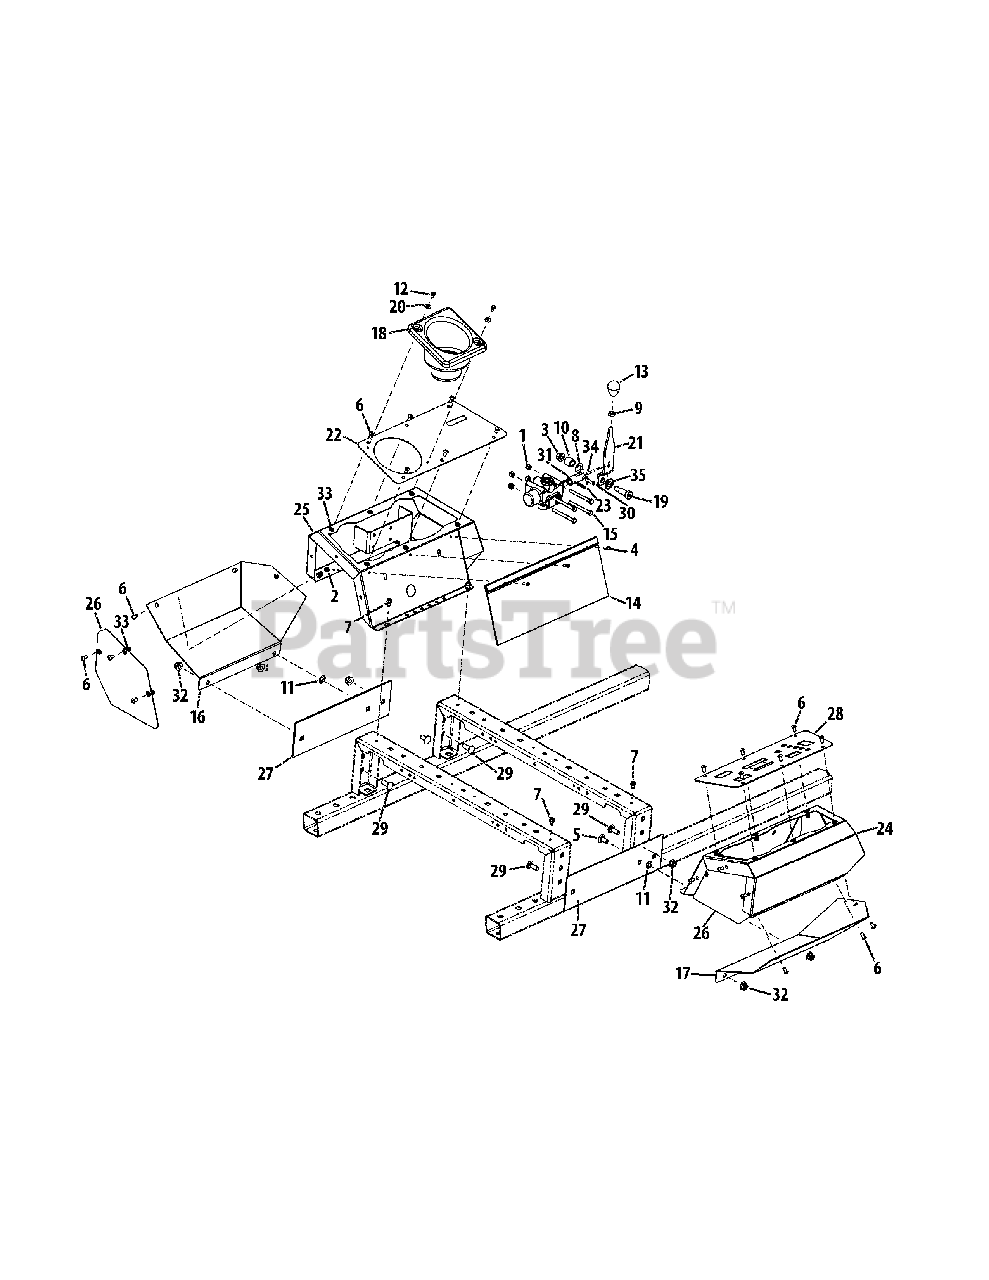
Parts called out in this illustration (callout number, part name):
1	Nut, 1/4-20
2	Nut, #10-32
3	Flange Counter Lock Nut, 3/8-16
4	Machine Screw, #10-32 x .625
5	Carriage Bolt, 3/8-16 x .75
6	Screw, 1/4-20 x .500
7	Hex Flange Screw, 1/4-20 x .500
8	Washer, .536 x .930 x .050
9	Jam Nut, 3/8-16
10	Spacer, .500 x .750 x .700
11	Push Nut, .335 x .780 x .015
12	Flange Screw, #10-32 x .500
13	Lever Knob, 3/8-16
14	Debris/Storage Bag
15	Hex Screw, 1/4-20 x 2.75
16	LH Lower Panel
17	RH Lower Panel
18	Cup Holder
19	Shoulder Bolt, 3/8-16 x .50 x 1.0
20	Washer, .300 x .550 x .047
21	Lift Valve Lever Bracket
22	LH Cover Control Plate
23	Spirol Pin, 3/16 x 1.0
24	RH Control Panel Assembly
25	LH Bracket Control Panel Assembly
27	Lower Side Panel
28	RH Cover Control Plate
29	Carriage Bolt, 3/8-16 x 1.00
30	Pin, .25 x .9375
31	Valve Link
32	Flange Lock Nut, 3/8-16
33	Nut, 1/4-20
34	Cotter Pin, 1/16 x .75
35	Bell Washer, .525 x 1.00 x .050
